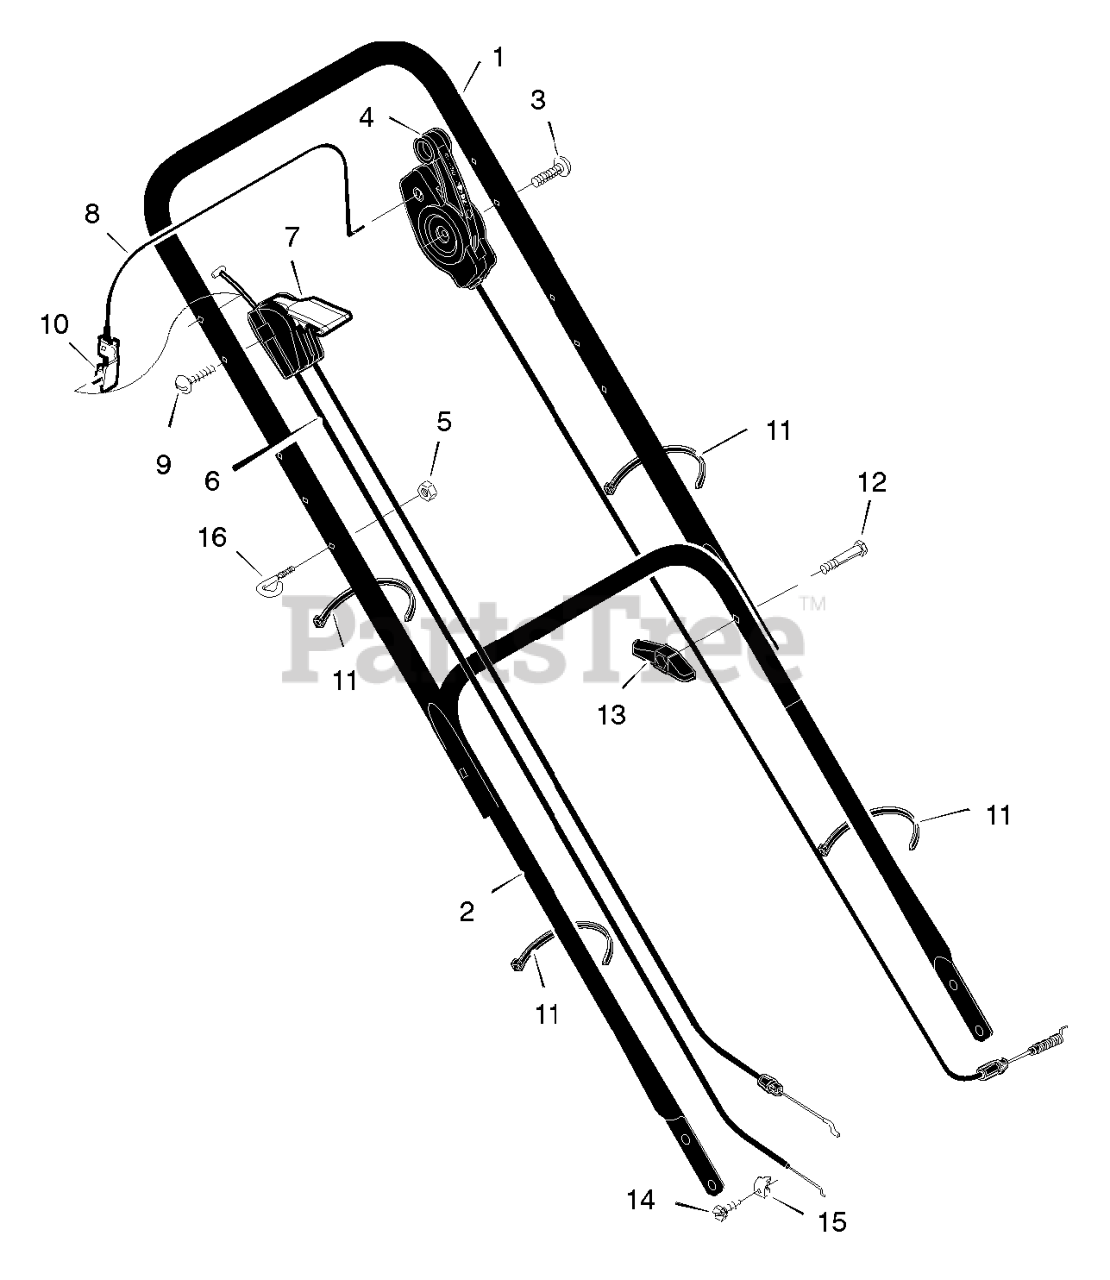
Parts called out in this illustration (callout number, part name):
1	Handle, Upper (Black)
2	Handle, Lower (Black)
4	Control, Drive
5	Locknut
6	Cable, Stop
7	Throttle Control
8	Lever, Stop
10	Bracket, Stop Lever
11	Fastener, Cable
13	Knob
16	Guide, Rope
